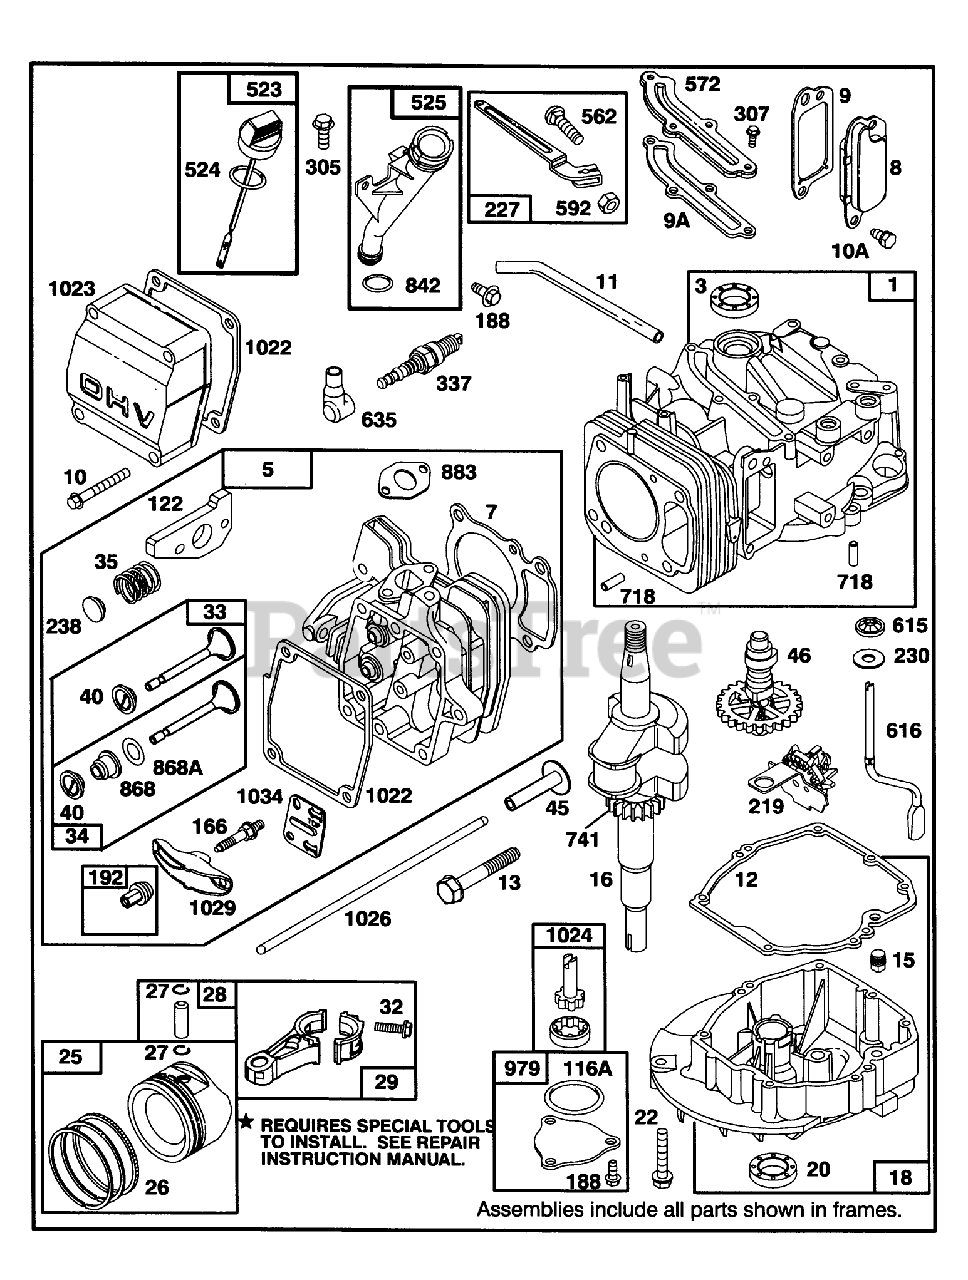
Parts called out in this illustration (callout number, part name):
3	SEAL - OIL
7	CYLINDER HEAD GASKET
9	BREATHER GASKET
9A	GASKET-BREATHER
12	ENGINE BASE GASKET
20	SEAL-OIL
104	FLOAT HINGE PIN
116	SEALING GASKET
116A	O RING SEAL
118	VALVE KIT - NEEDLE
121	CARBURATOR OVERHAUL KIT
122	ADAPTER ASSEMBLY
127	PLUG
134	Valve-Float (Includes Seat)
137	FLOAT BOWL GASKET
163	AIR CLEANER GASKET
358	GASKET SET
524	O-RING
634	SEAL WASHER
842	O-RING
868	SealAssy-Valve
868A	Seal-Valve
883	EXHAUST GASKET
977	CARBURATOR GASKET SET
1022	ROCKER COVER GASKET
1039	FLOAT LIMITER
1041	SEAL - FOAM
